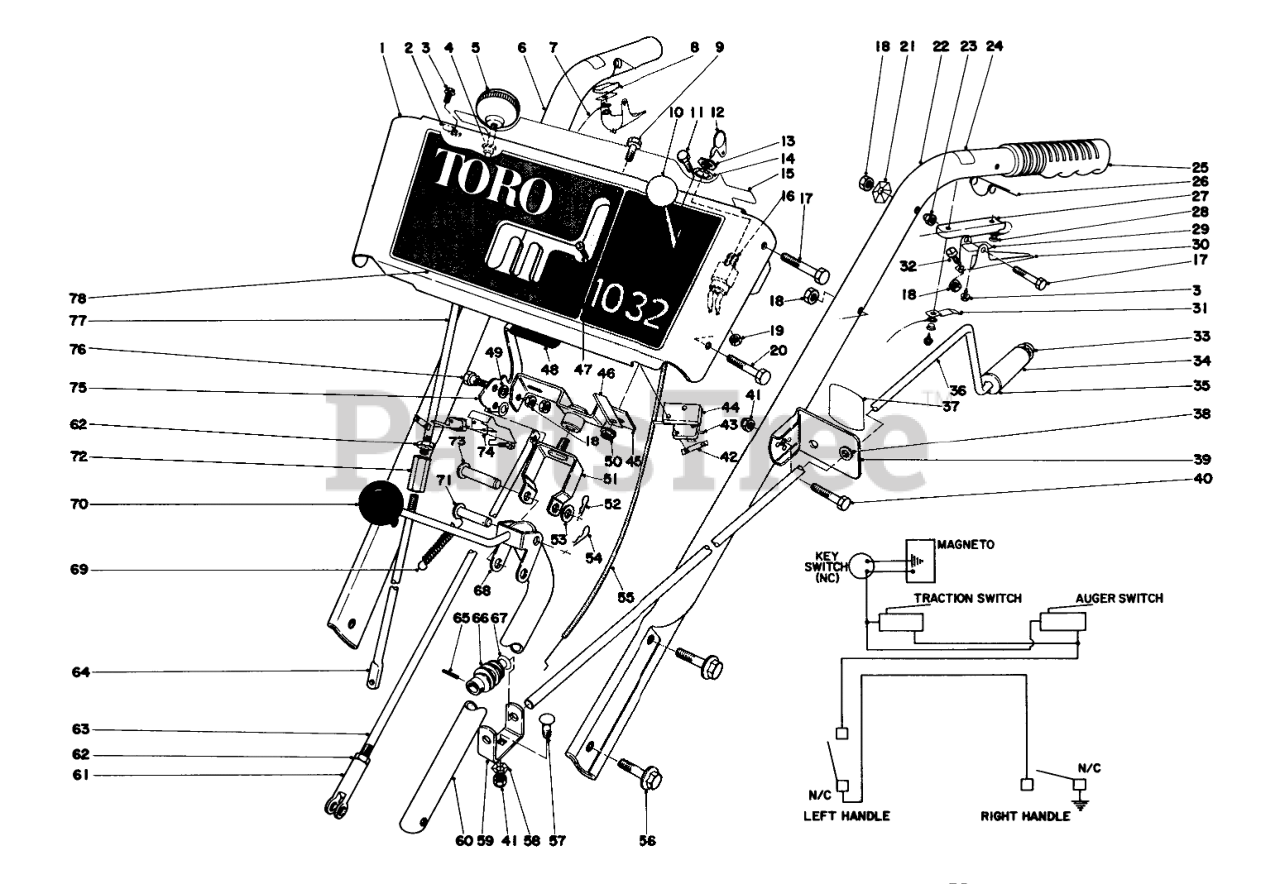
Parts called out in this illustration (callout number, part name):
1	Escutcheon Plate (Incl. Ref. #15 & 78) (Model #38070)
2	PLASTIC CLIP
3	SCREW
4	Bushing
5	KNOB-LEVER
6	Handle Right
7	Wire Harness
8	Insulator
9	SCREW-HH
10	Knob
11	HEX HEAD SEMS 10-24X1/2
12	Key
13	NUT-HH
14	WASHER-TOOTH, INTERNAL
15	BACK ESCUTCH DECAL
16	SWITCH-ON / OFF
17	SCREW-HH
18	NUT-LOCK, CONE
19	Nut
20	SCREW-HH
21	Washer
22	LEFT HANDLE
23	NUT-CAP
24	INTERLOCK DECAL
25	Grip Handle
26	INTERLOCK SPRING
27	DUAL BRKT INSULATOR
28	WASHER INSULATOR
29	INTERLOCK CONTACT
30	SAFETY INTRLOCK LEVER
31	CONTACT BRACKET
32	NYLON SCREW 1/4 20
33	RETAINER-PUSH ON
34	CHUTE CONTROL GRIP
35	WASHER-FLAT
36	ROD CHUTE CONTROL
37	CHUTE DECAL
39	Bracket Chute Control Mounting (Incl. Ref. 4 & 37)
40	SCREW-HH
41	NUT-LOCK, NI
42	NUT-SPEED
43	MICRO SWITCH
44	SWITCH MTG PAD
45	SWIVEL BLOCK WA
46	Retainer Wire
47	SCREW-SPH
48	AUGER CLUTCH HND GRIP
49	WASHER-PLAIN
50	NUT-LOCK, HHF
51	PIVOT BRKT WA
52	PIN-HAIR
53	WASHER-FLAT
54	PIN-COTTER
55	Throttle Contrl
56	SCREW-HHF
57	SCREW-CARR
58	WASHER-LOCK
59	WORM BRACKET
60	Rod Traction Shift
61	Clevis
62	NUT-HJ
63	DRAG LINK
64	LOWER WHL CLUTCH ROD
65	PIN-SPRING
66	GEAR-WORM, CHUTE
67	WASHER-SPRING
68	SHIFT ROD WA
69	CONT ROD SPRING 0
71	PIN-CLEVIS
72	WHL ROD COUPLING
73	PIN-CLEVIS
74	SWITCH BRKT
75	Auger Clutch Handle
76	SCREW-SHOULDER
77	UP WHEEL CLUTCH ROD
78	Decal Escutcheon (Model 38070)
